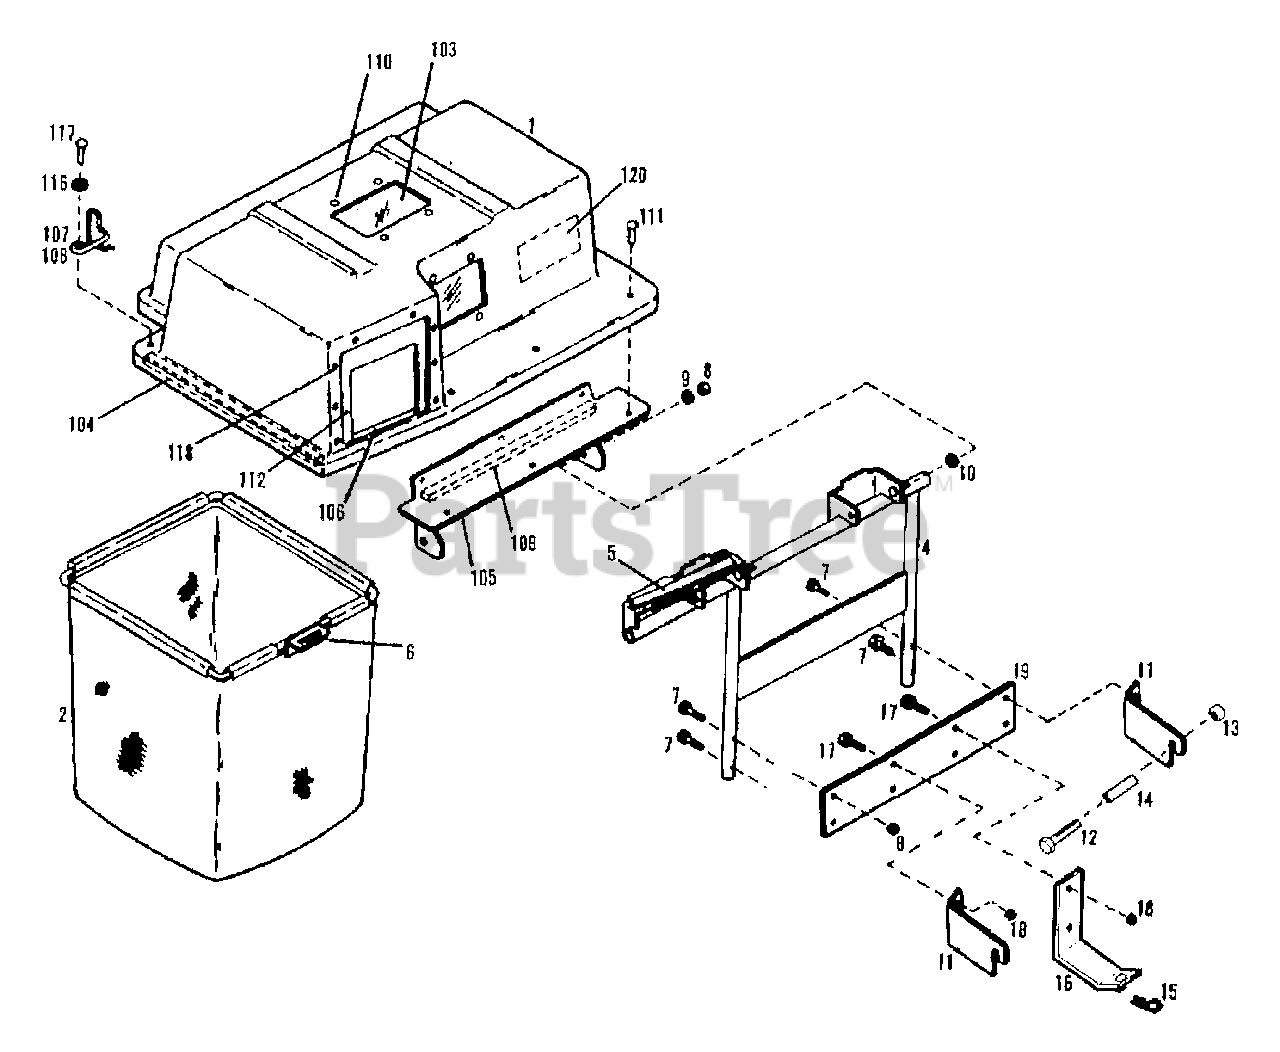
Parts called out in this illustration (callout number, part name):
1	ASSM-CVR GRASS BAG
2	ASSM-GRASS BAG
4	ASSM-BAG SUPPORT
5	SEAL-COVER 9.5"
6	ASSM-FRAME GRASSBAG
7	SCR-HH 5/16-18X2.00
8	NUT-TOP/LK 5/16-18 ZP
9	WASHER-FLAT 5/16 SAE
10	WASHER-.87X.34X.06 NYLON
11	PLATE-SIDE MOUNTING
12	SCR-HH 1/2-13X1.5 G5 ZP
13	NUT-TOP LOCK 1/2-13 ZP
14	SPACER-ATTACHMENT
15	PIN-HITCH .125X2.56 ZP
16	SUPPORT-MOUNTING
17	SCR-HFLK 5/16-18X1.00 ZP
18	NUT-HFLK 5/16-18 ZP
19	PLATE-SUPPORT
103	WINDOW
104	SEAL-COVER
105	ASSM-HINGE SUPPORT
106	CHUTE REINFORCEMENT
107	COVER-LOCK RH
108	COVER-LOCK LH
110	RIVET-POP
111	RIVET-POP 3/16"DIA
112	GASKET-CHUTE
116	WASHER-.88X.2X.059
117	RIVET-POP 3/16X1/2
118	RIVET-POP .125
120	DECAL-INST
